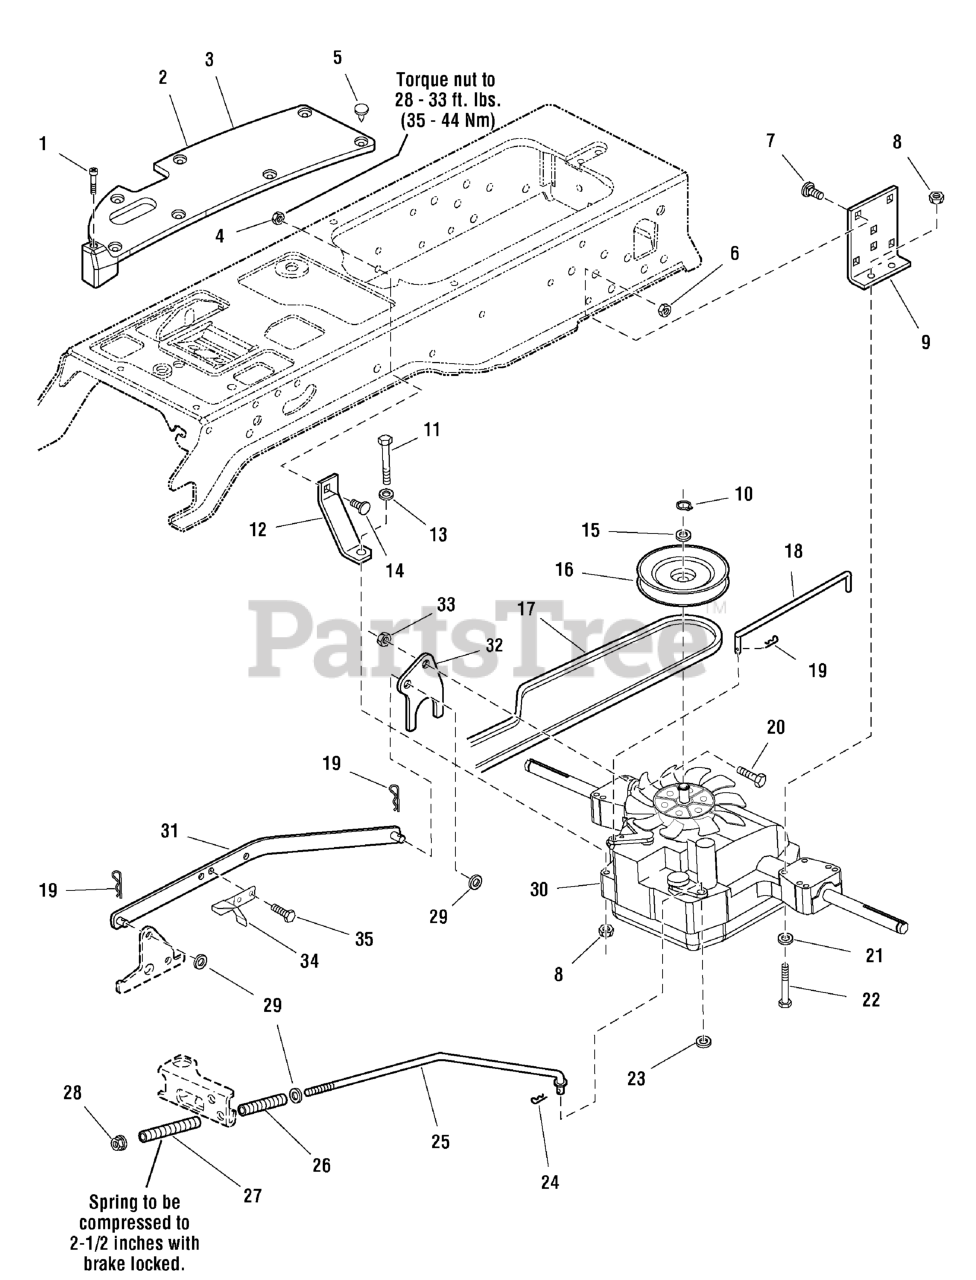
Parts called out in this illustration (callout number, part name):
1	SCREW, Pan Head Torx Taptite, 1/4-20 x 1-1/4, Black
2	PAD, Footrest, LH, without Differential Lock
3	PAD, Footrest, RH
4	NUT, Hex KEPS, 5/16-18, Black
5	FASTENER, Panel
6	NUT, Hex KEPS, 3/8-16, Black
7	CARRIAGE BOLT, 3/8-16 x 1, Black
8	NUT, Hex Flange ESNA, 5/16-18, Black
9	SUPPORT, Transmission
10	RING, Snap, Transmission
11	CAPSCREW, Hex Head 5/16-18 x 2 G5
12	STRAP, Torque
13	WASHER, 5/16, Black
14	BOLT, Carriage, Short Neck, 5/16-18 x 1
15	WASHER, 1/2
16	PULLEY & HUB ASSEMBLY
17	V-BELT, Drive
18	ROD, Transmission Release
19	PIN, Quick
20	CAPSCREW, Hex Head, 5/16-18 x 2
21	WASHER, 5/16
22	CAPSCREW, Hex Head, 5/16-18 x 2-3/4, Black
23	WASHER, 15/32 x 15/16, Black
24	PIN, Cotter, Black
25	ROD, Brake
26	SPRING, Compression, 3-1/4" Long, Black
27	SPRING, Compression, 3-5/8" Long, Black
28	NUT, Hex FlangeESNA, 3/8-16, Black
29	WASHER, 3/8, Black
30	TRANSMISSION ASSEMBLY, K57, without Pulley
31	CONTROL ARM ASSEMBLY
32	ARM, Control
33	NUT, KEPS Lock, 5/16-18
34	ACTUATOR, Switch
35	CAPSCREW, Hex Head Taptite, 5/16-18 x 1/2
